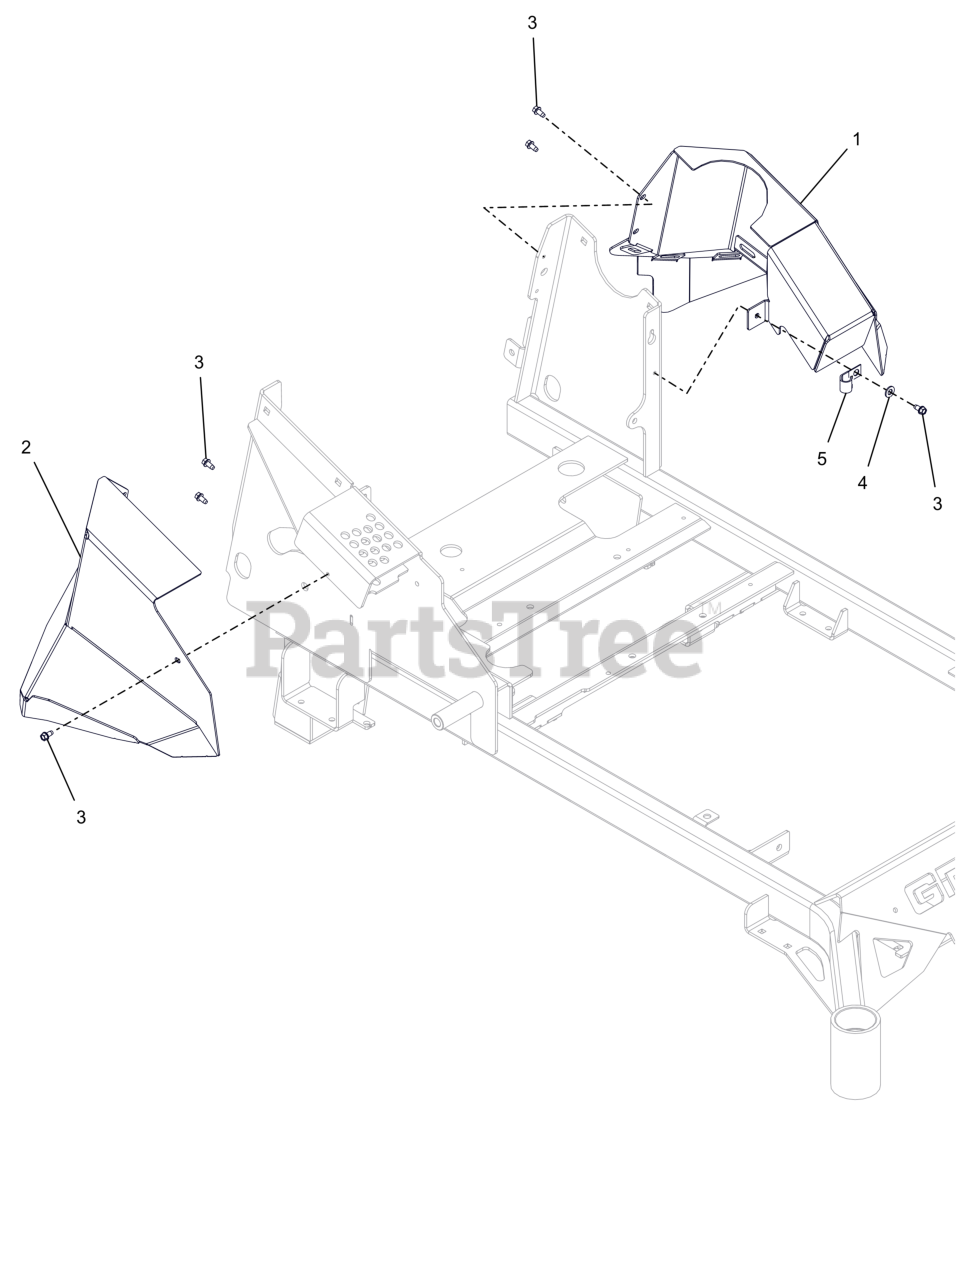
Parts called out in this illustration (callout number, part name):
1	WLDMT, LH FENDER (BLACK)
2	WLDMT, RH FENDER (BLACK)
3	SCR-TAP .25-20X.50 HWH ZCC
4	WSHR,FLT .344X.688X.065 ZCC
